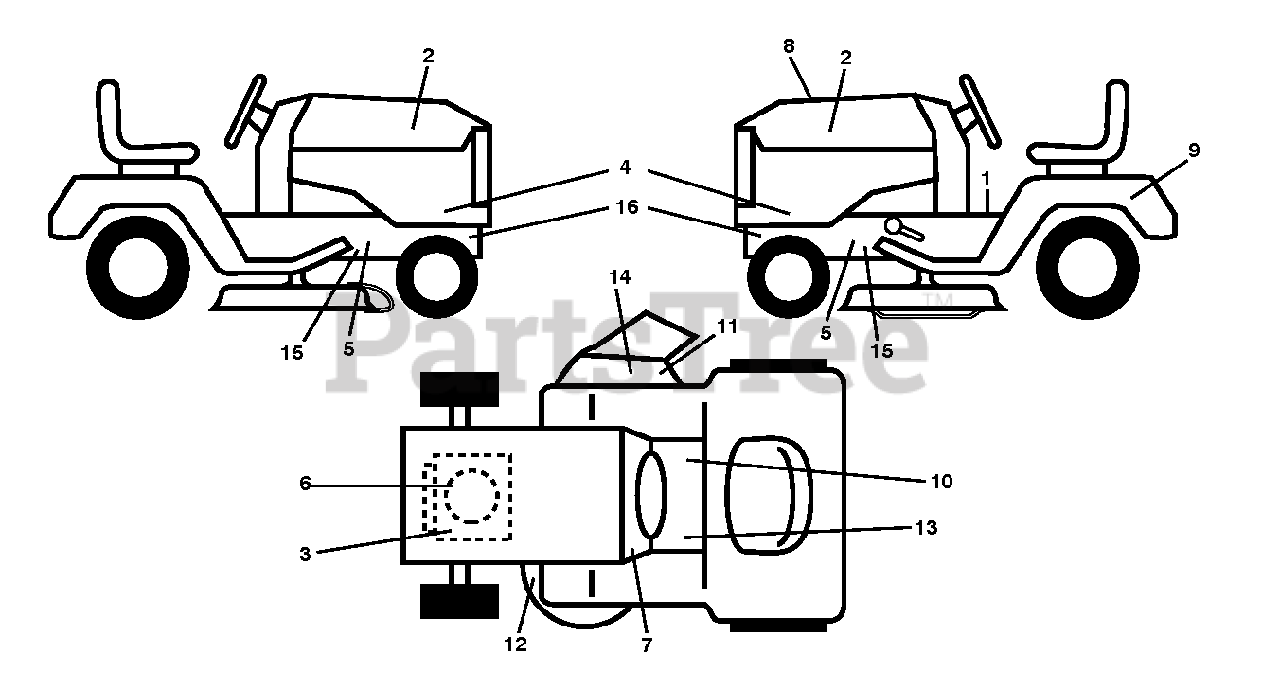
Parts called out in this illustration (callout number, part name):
1	DECAL.READ.OWN.MAN.SYMBOL.LT
2	DECAL.BADGE.170MM.TEXTLOGO.
3	DECAL.ENGINE.WARNING
4	DECAL.SDPNL.HUSQLT.TS238
5	DECAL.CHASSIS.HOT.MUFFLER
6	DECAL.ENG.BS.500CC.ENDR.382273
7	DECAL.SNOWFLAKE.MS498.HUSQ
8	DECAL.RPL.BSM31.HS.TLW.97.K46
9	DECAL BTRY SYMBOLS
10	DECAL.PARKING.BRAKE.SADDLE.LT
11	DECAL.DFLCTR.WARNNG.CTFNGR.SYM
12	DECAL.DECK.SCH.36,38,94.NONCR
13	DECAL.FNDR.SDLE.BRAKE.CLUTCH.6
14	DECAL, DECK DEFLECTOR, WARNING
15	DECAL.WARNING.SERVCE/FIRE
16	DECAL.WARNING.SERVCE/FIRE
